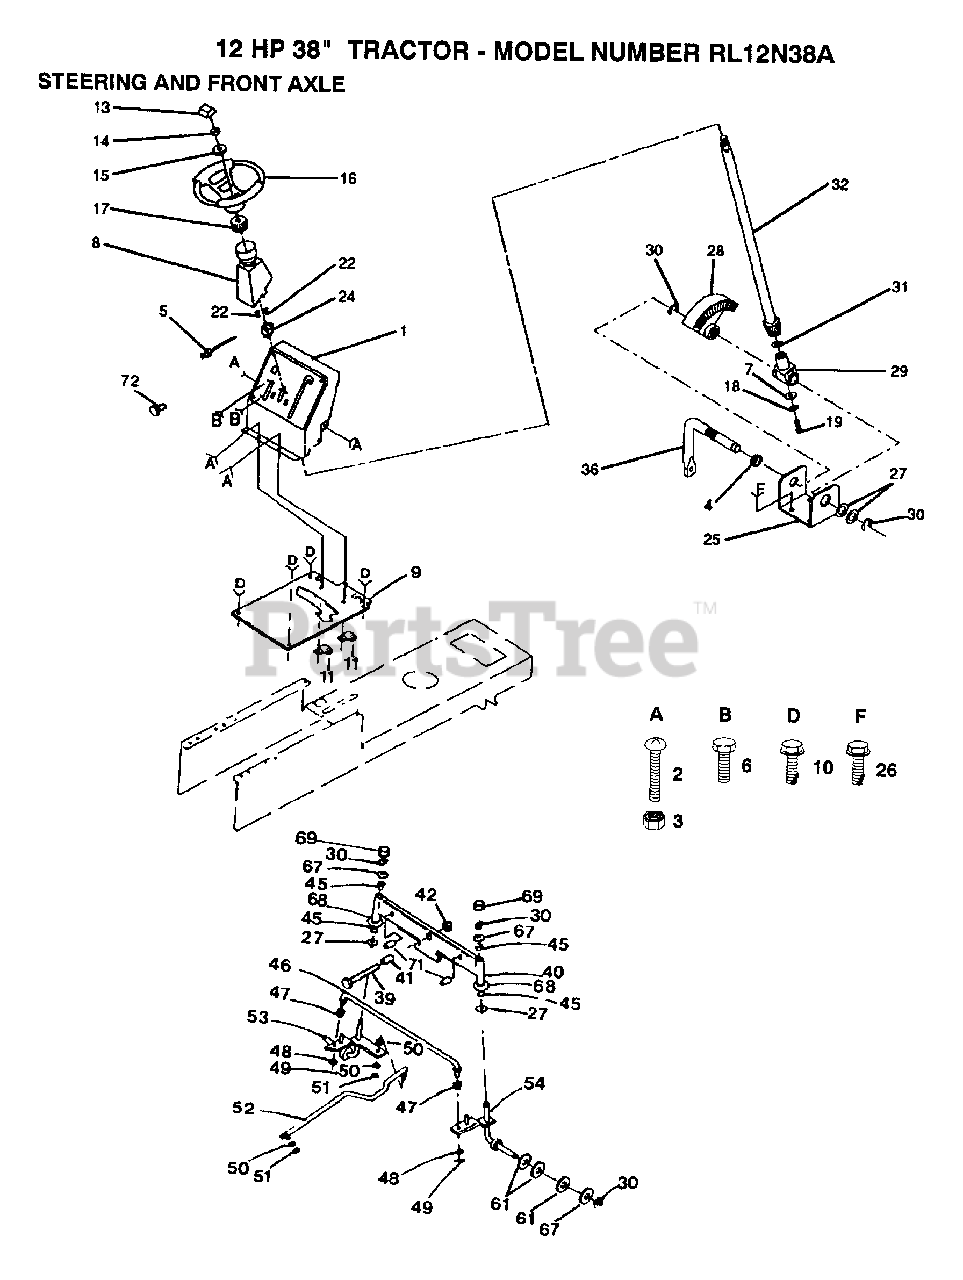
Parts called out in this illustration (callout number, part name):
2	SCREW
4	NYLINER T
6	SCREW LT
8	"TUBE, STR SHAFT"
10	SCREW LT
11	CLIP T
13	ST WHL INSERT CAP
14	GRIPCO NUT
15	WASHER T
17	ADAPTER-WHEEL LT
18	LOCKWASHER
19	"SCREW,SPECIAL"
25	"BRKT,STEERING"
26	SCREW
27	WASHER .T
29	SUPPORT.SHAFT
30	RING
31	THRUST WASHER
32	SHAFT ASM
39	BOLT HEX 5/8-11
41	BEARING
45	COL. SRTG. BEAR.
46	TIE ROD
47	BUSHING.DRAGLINK
48	WASHER
49	COTTER PIN
50	LOCKWASHER
53	SPINDLE LH
54	SPINDLE RH
61	WASHER
67	WASHER
68	WASHER
69	CAP
71	AXLE PIN
72	PLUG BUTTON T
